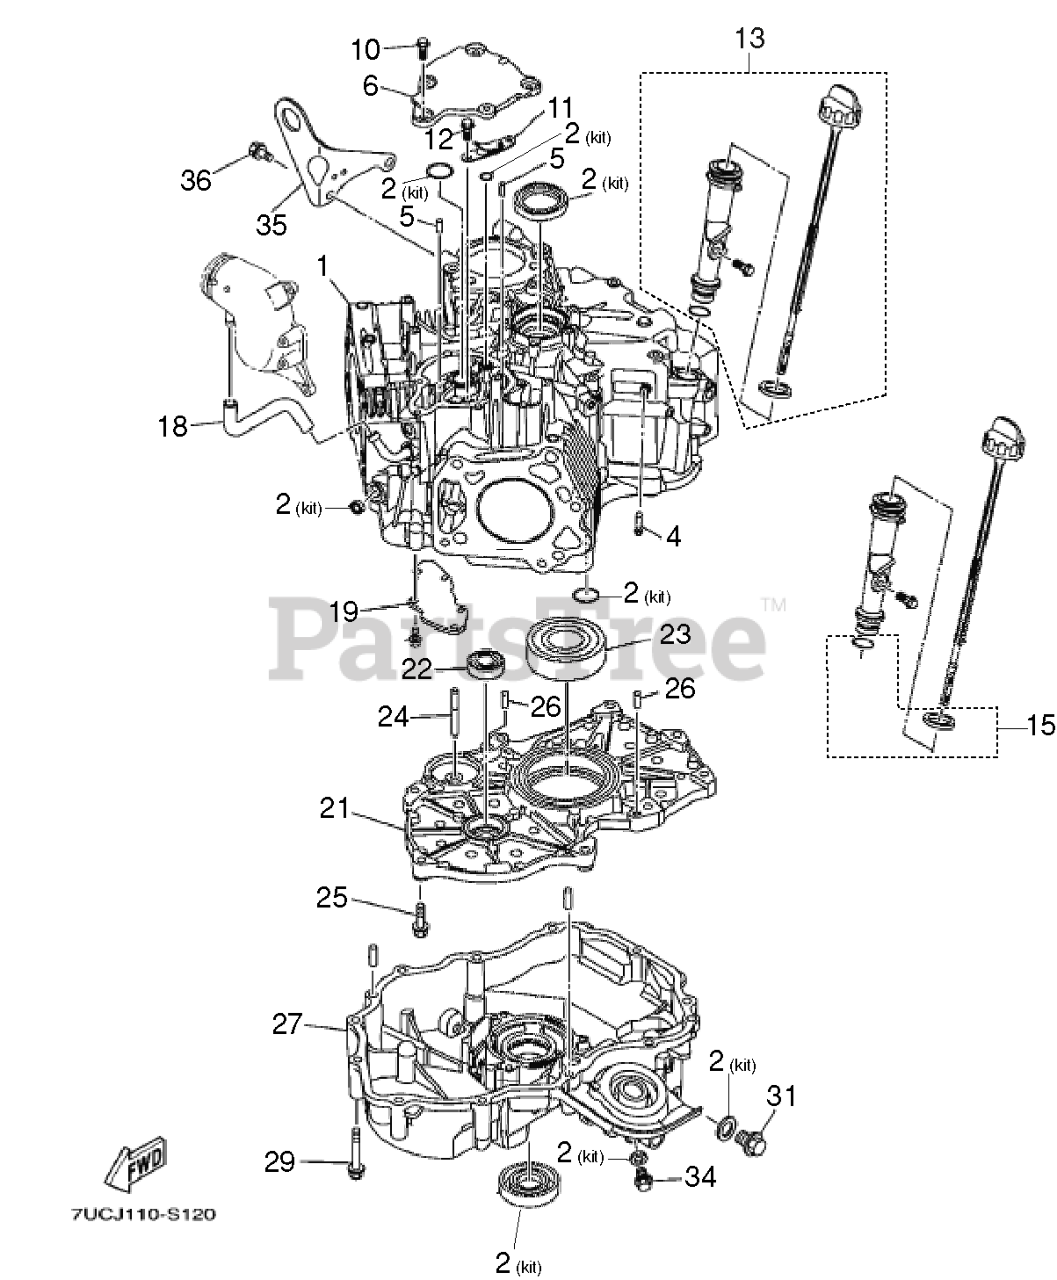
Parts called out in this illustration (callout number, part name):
1	CRANKCASE ASSY 1 YAMAHA PN: 7U
2	SEALING CRANKCASE SEALING KIT
4	PIPE JOINT YAMAHA PN: 7UD-E448
5	PIN SERVICE KIT  X10
6	COVER BREATHER YAMAHA PN: 7UD-
10	BOLT YAMAHA PN: 95822-06016
11	VALVE ASSY REED YAMAHA PN: 7UD
12	BOLT YAMAHA PN: 95822-06014
15	GASKET KIT
18	HOSE YAMAHA PN: 90445-13811
19	COVER 2 YAMAHA PN: 7UD-E5423-0
21	COVER CRANKCASE 1 YAMAHA PN: 7
22	BEARING YAMAHA PN: 93306-003X
23	BEARING YAMAHA PN: 93306-309Y
24	SHAFT FLYWEIGHT YAMAHA PN: 7UD
25	BOLT SERVICE KIT X10
26	PIN DOWEL YAMAHA PN: 99530-080
27	COVER CRANKCASE 2 YAMAHA PN: 7
29	BOLT SERVICE KIT X10
31	PLUG STRAIGHT SCREW YAMAHA PN:
34	BOLT YAMAHA PN: 90105-10715
35	HANGER ENGINE 2 YAMAHA PN: 7UC
36	BOLT YAMAHA PN: 95822-08020
